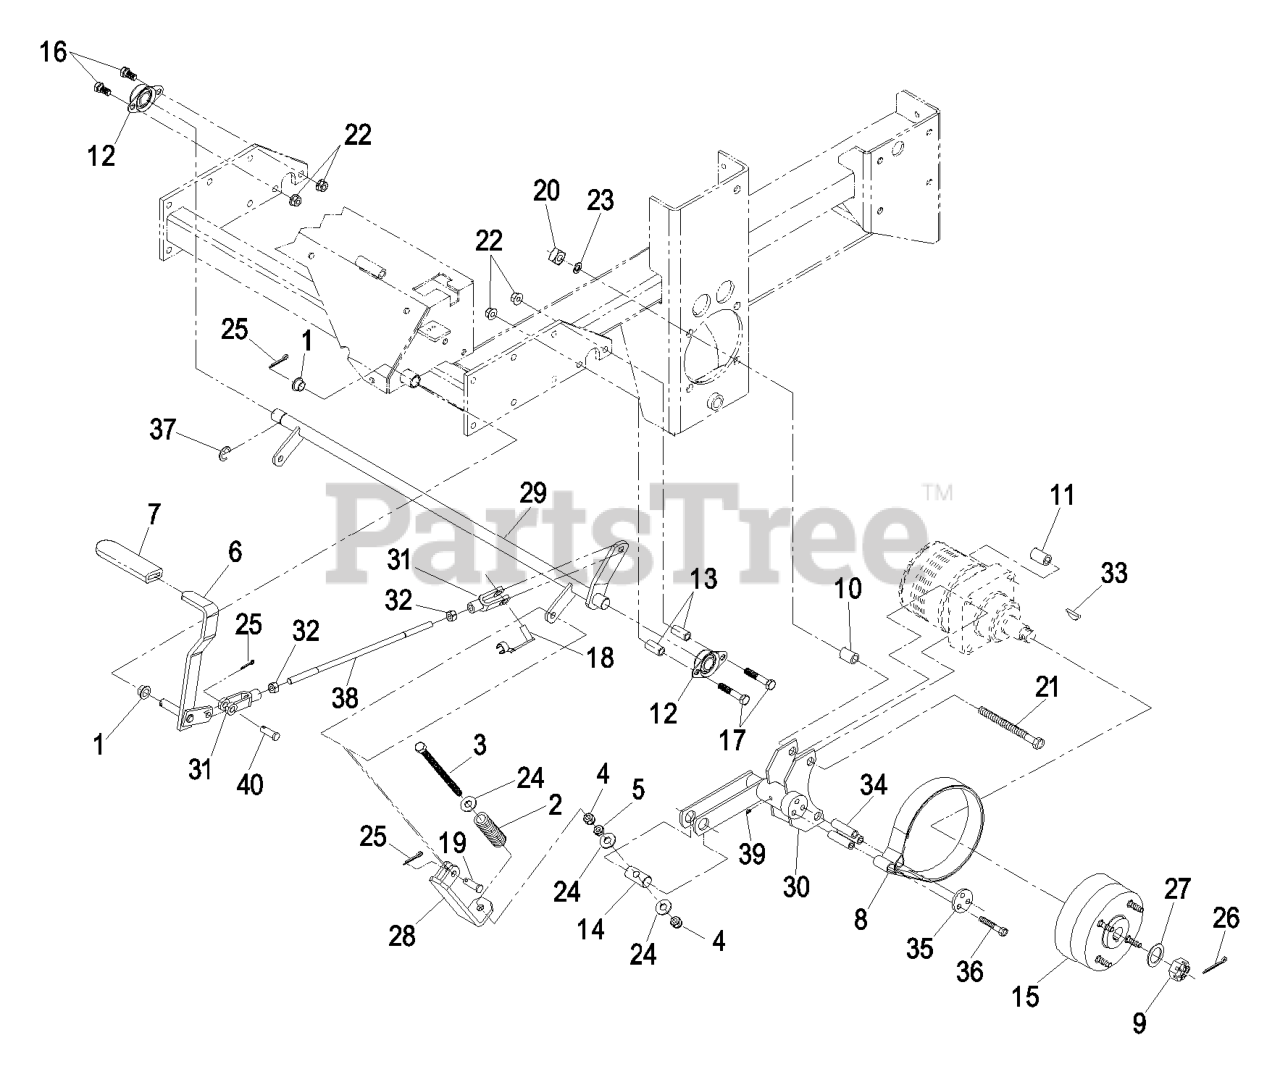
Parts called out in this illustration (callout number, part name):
1	BEARING-CONTROL
2	SPRING-BRAKE
3	BOLT-TAP, HH
4	NUT-LOCK, NI
5	NUT-JAM
6	BRAKE LEVER AND GRIP ASM
7	GRIP-LEVER
8	BAND,BRAKE
10	SPACER-WHEEL, SHORT
11	SPACER-WHEEL, LONG
12	BEARING-FLANGE, SIDE
13	SPACER-RETAINER, BRAKE
14	PIN-TRUNION
15	WHEEL HUB ASM
16	SCREW-HH
17	SCREW-HH
18	PIN-SPRING, CLEVIS
19	PIN-CLEVIS
21	SCREW-HH
22	NUT-HHF, WHIZ
23	WASHER-LOCK
24	WASHER-FLAT
25	PIN-COTTER
26	PIN-COTTER
27	WASHER-SPACER
28	LINKAGE-BRAKE, LOWER
29	SHAFT-BRAKE
30	BRAKE-NARROW
31	YOKE-LINKAGE, BRAKE
32	NUT-HEX
33	KEY-WOODRUFF
35	RETAINER-BAND, BRAKE
36	SCREW-HH
38	ROD-BRAKE
39	FITTING-GREASE
40	PIN-CLEVIS
